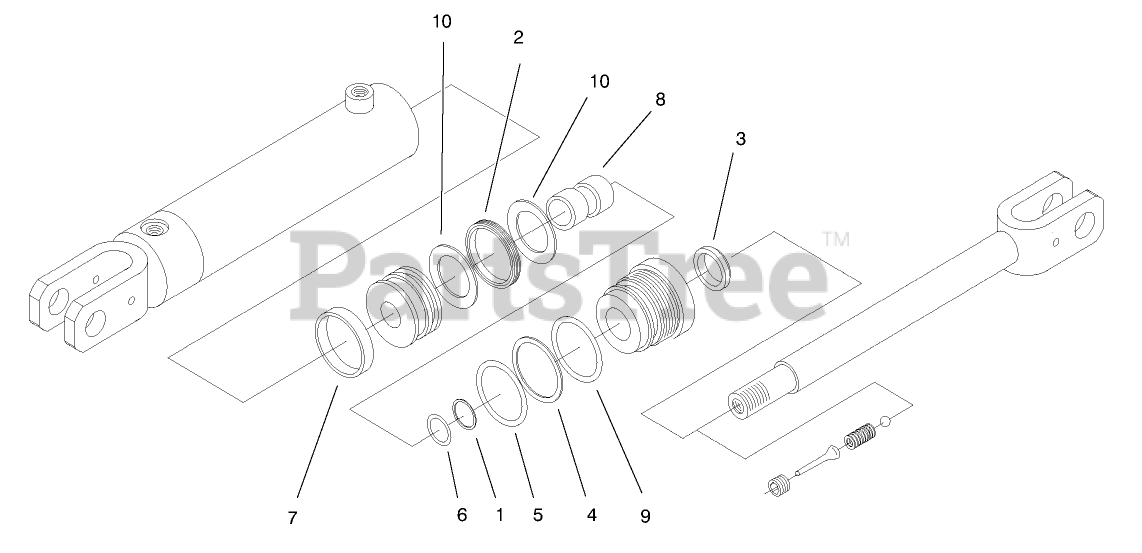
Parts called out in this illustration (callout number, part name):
2	PSP Seal
3	Rod-Wiper
6	Polypak
7	Ring-WEAR
8	Ring-WEAR
